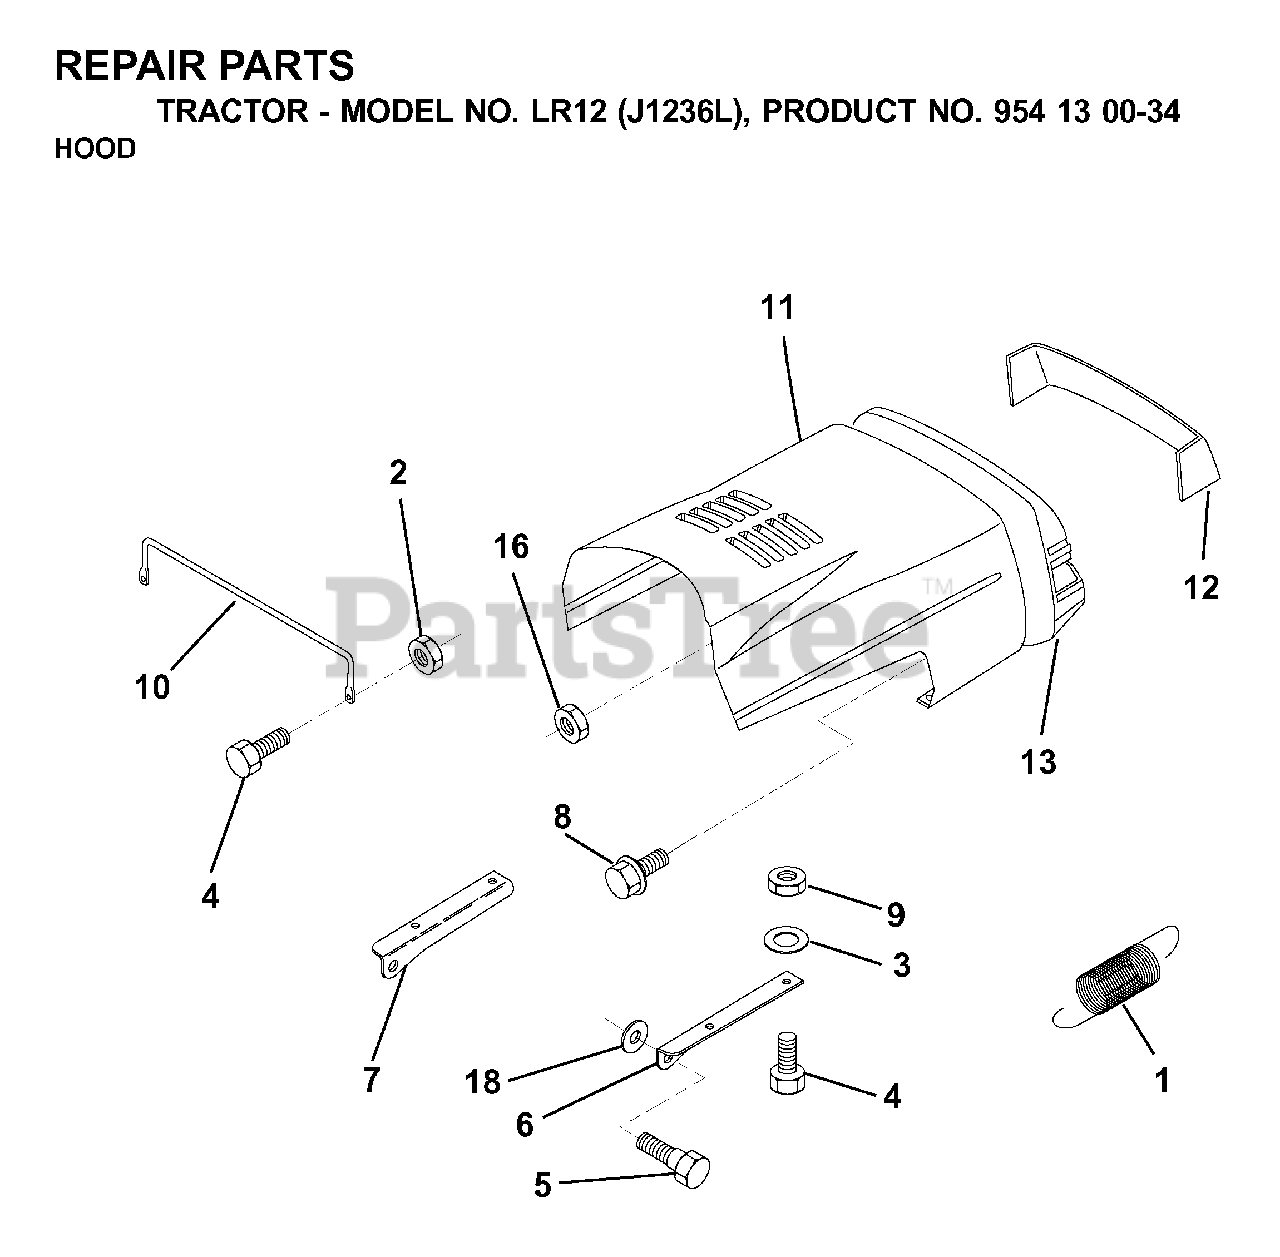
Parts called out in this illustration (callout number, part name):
1	EXT SPRING
2	NUT
4	BOLT
6	BRKT HOOD RH
7	BRKT HOOD LH
8	SCREW
9	LOCKNUT
10	BRACE,HOOD
18	WASHER
